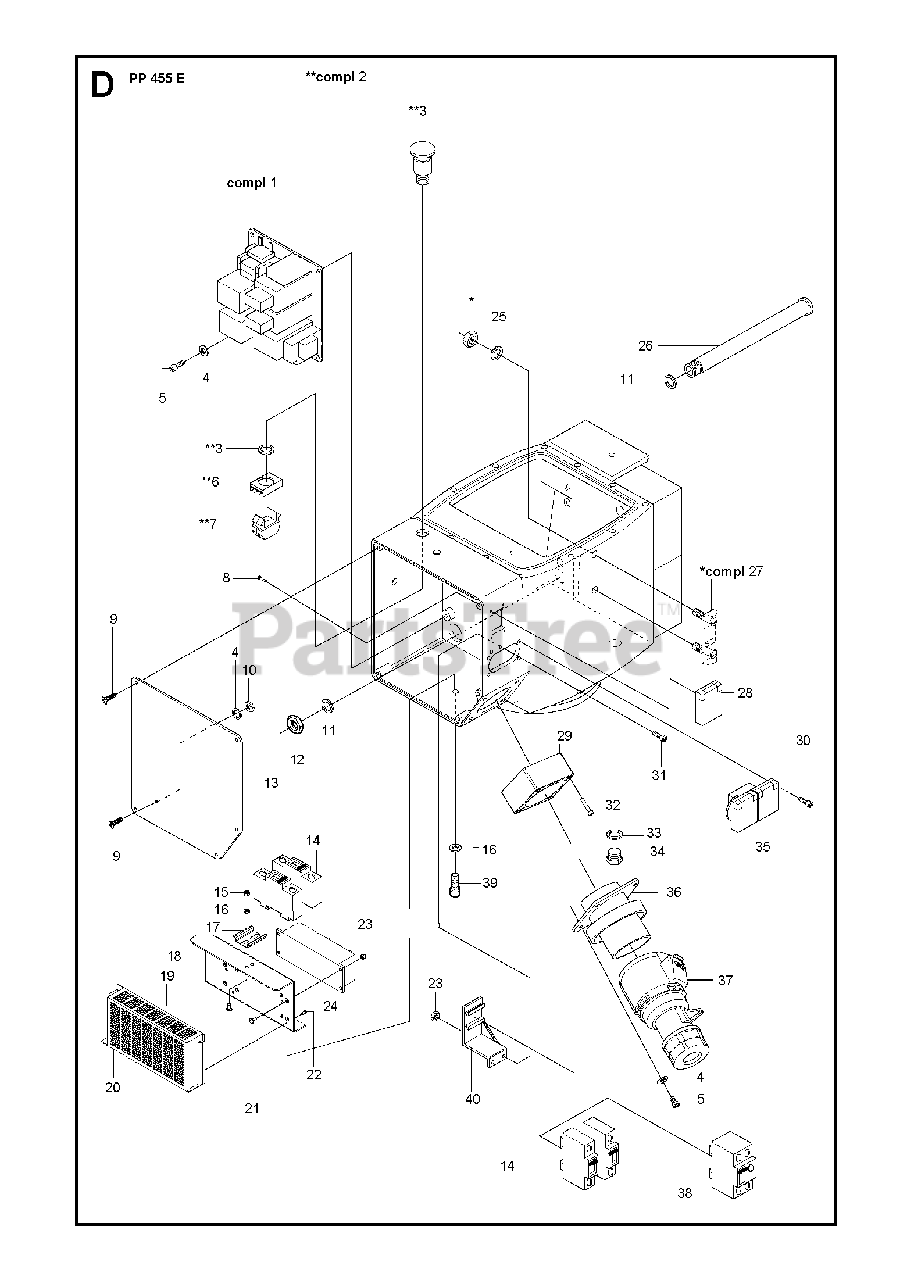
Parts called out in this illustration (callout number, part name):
1	ELECTRICAL SYSTEMCompl. US 440V
1	EL. PLATE COMPL. 230/400V NOCompl. NOR 230V/400V
1	EL. PLATE COMPL. 200V JAPANCompl. JAP 200V
13	PROTECTIVE PLATE
14	FUSEONLY WITH 230V OUTLET
15	HEXAGON LOCKING NUT
16	WASHER
23	HEXAGON LOCKING NUT
25	SEALING WASHER
35	SOCKET 230V DOUBLEONLY WITH 230V OUTLET
36	ELECTRIC INLET 220V/125A JPN200V
37	SOCKETAUS-US/CAN 440V
38	GUARDONLY WITH 230V OUTLET
